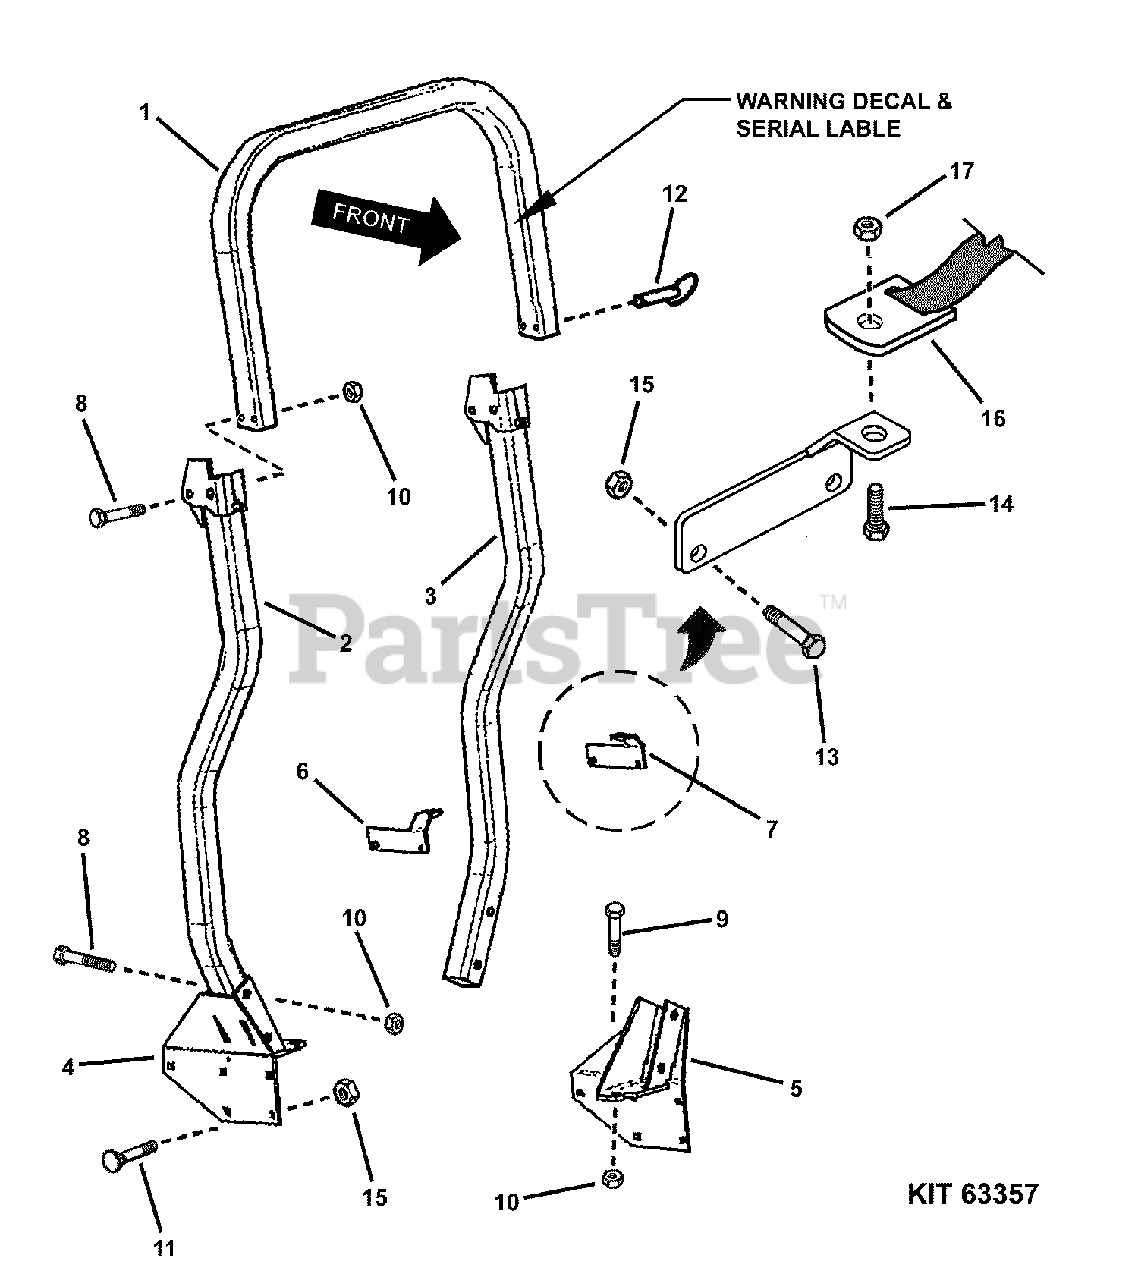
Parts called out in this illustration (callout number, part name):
1	TOP LOOP
2	RH POST
3	LH POST
4	RH MOUNT (Weldment)
5	LH MOUNT (Weldment)
6	RH SEATBELT MOUNT
7	LH SEATBELT MOUNT
8	BOLT, 1/2-13 x 3-1/4" Hex Head, GR 5
9	BOLT, 1/2-13 x 1-1/2" Hex Head, GR 5
10	NUT, 1/2-13 Hex Center Lock
11	BOLT, 3/8-16 x 1-1/2" Square Neck Carriage, GR 5
12	HINGE PIN, 1/2" x 2.76"
13	BOLT, 3/8-16 x 1-1/2" Hex Head, GR 5
14	BOLT, 7/16-20 x 1" Hex Head, GR 5
15	NUT, 3/8-16 Hex Center Lock
16	SEATBELT, Belt Retractor
16	SEATBELT, Buckle w/Cable
